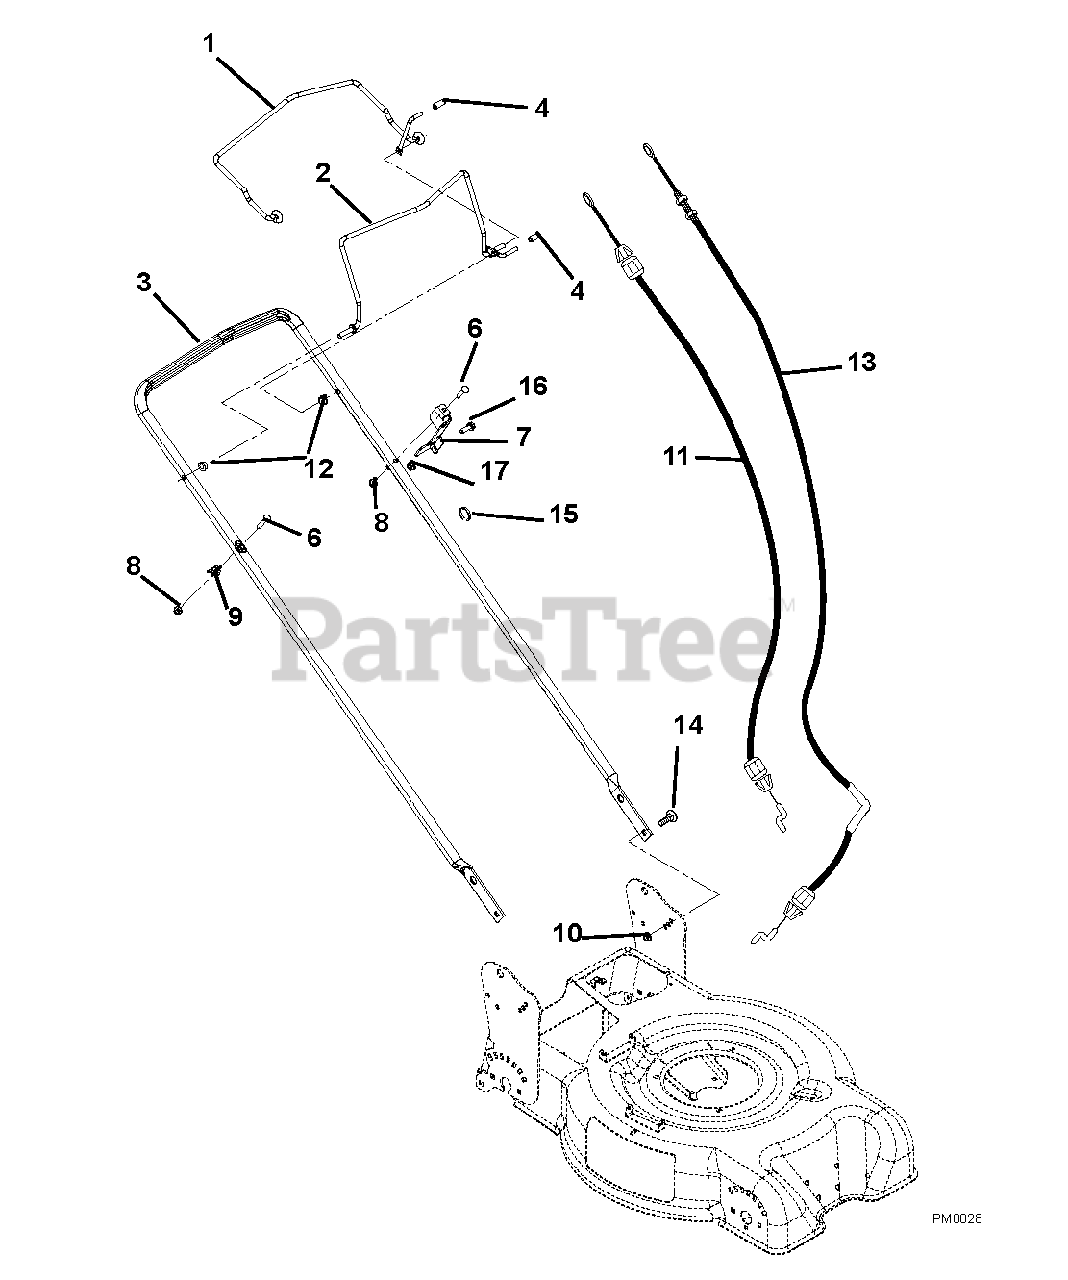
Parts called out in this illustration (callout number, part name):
1	Bail, Drive
2	Bail, Operator Presence
3	Handlebar
4	Cap, Vinyl .25 I.D.
5	Cap, Vinyl .25 I.D.
6	Bolt, Round Head Square Neck .25-20 x 1.25
7	Anchor, Cable Thumb Adjustment
8	Nut, Locking-Top-Flange .25-20
9	Guide, Pullcord
10	Nut, Flange Spinlock .312-18
11	Cable, Operator Presence
12	Bushing, Flange .325 x .444 x.440 x.560
13	Cable, Traction Thumb Adjustment
14	Bolt, Round Head Square Short Neck .31-18 x .75 Grade 5
15	Clip, Conduit
16	Bolt, Hex .25-20 x 1.25 Grade 5
17	Nut, Locking-Top-Flange .25-20
